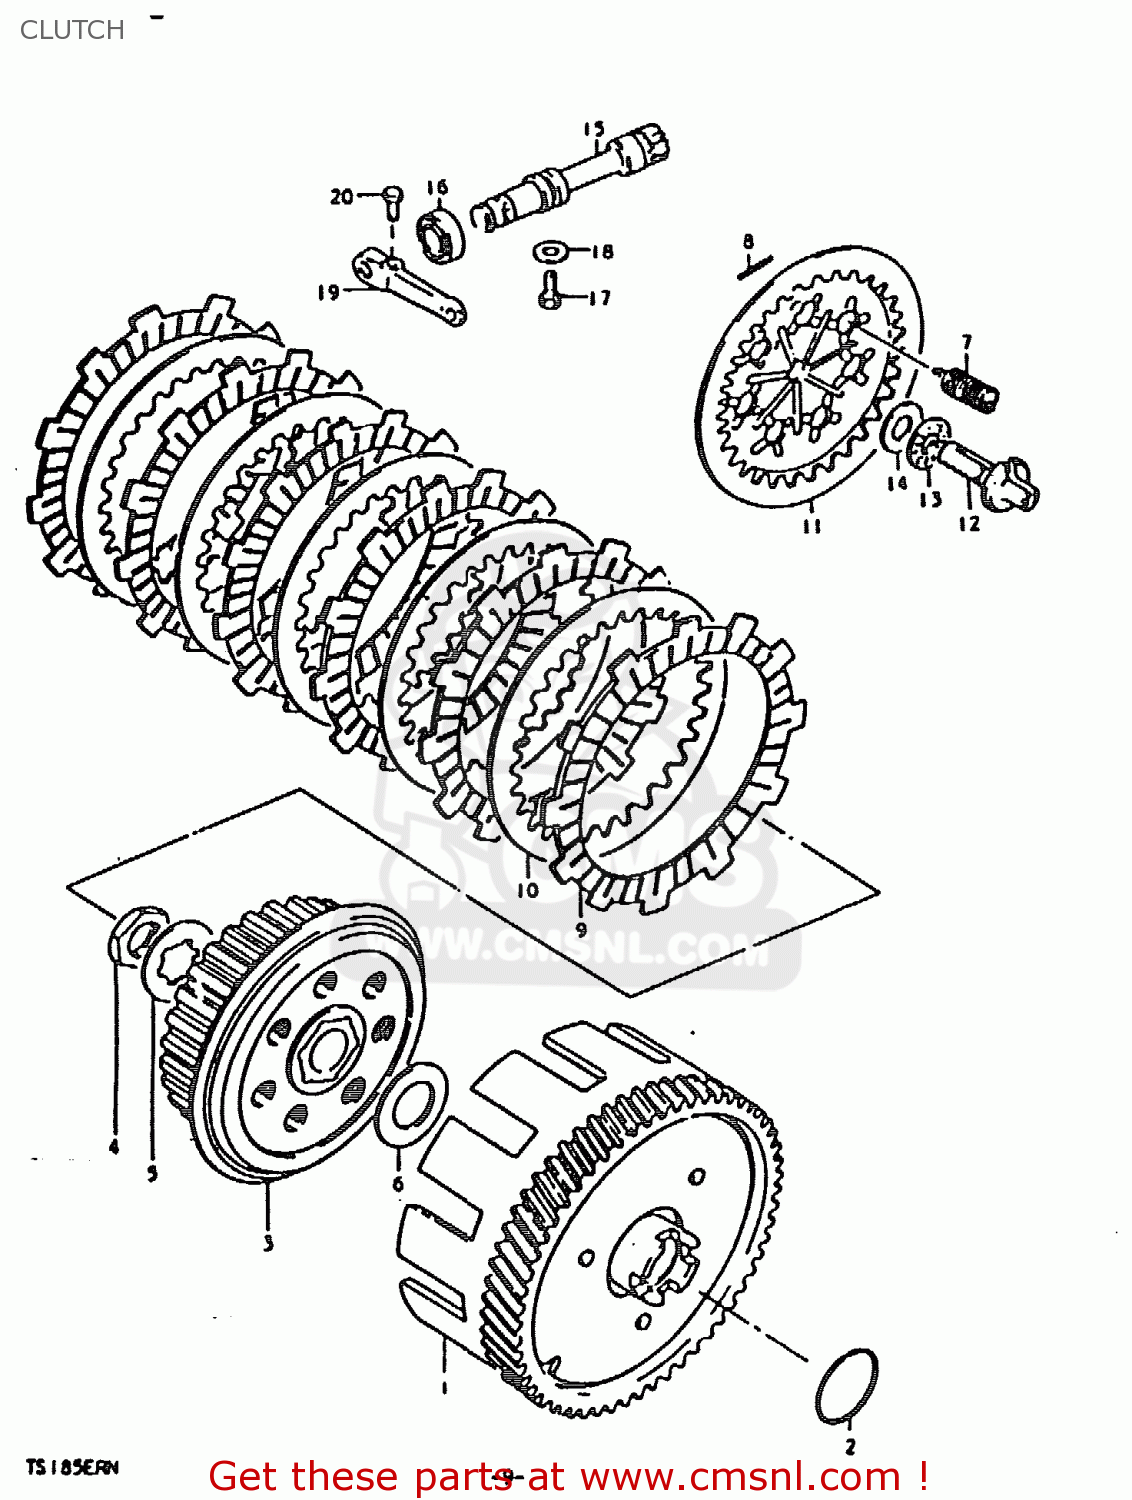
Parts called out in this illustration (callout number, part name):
1	GEAR ASSEMBLY,PRIMARY DRIVE
2	SPRING
3	HUB,CLUTCH SLEEVE
4	NUT
5	WASHER,LOCK
6	WASHER
7	SPRING
8	PIN(2.5X19.8)
9	PLATE,CLUTCH DRIVE
10	PLATE,CLUTCH DRIVEN (NAS)
11	PLATE,CLUTCH PRESSURE
12	RACK,CLUTCH RELEASE
13	BEARING(10X22X2.8)
14	WASHER(10.1X21.4X0.8)
15	PINION,CLUTCH RELEASE
16	OIL SEAL
17	BOLT(6X12)
18	WASHER
19	ARM,CLUTCH RELEASE
20	BOLT
